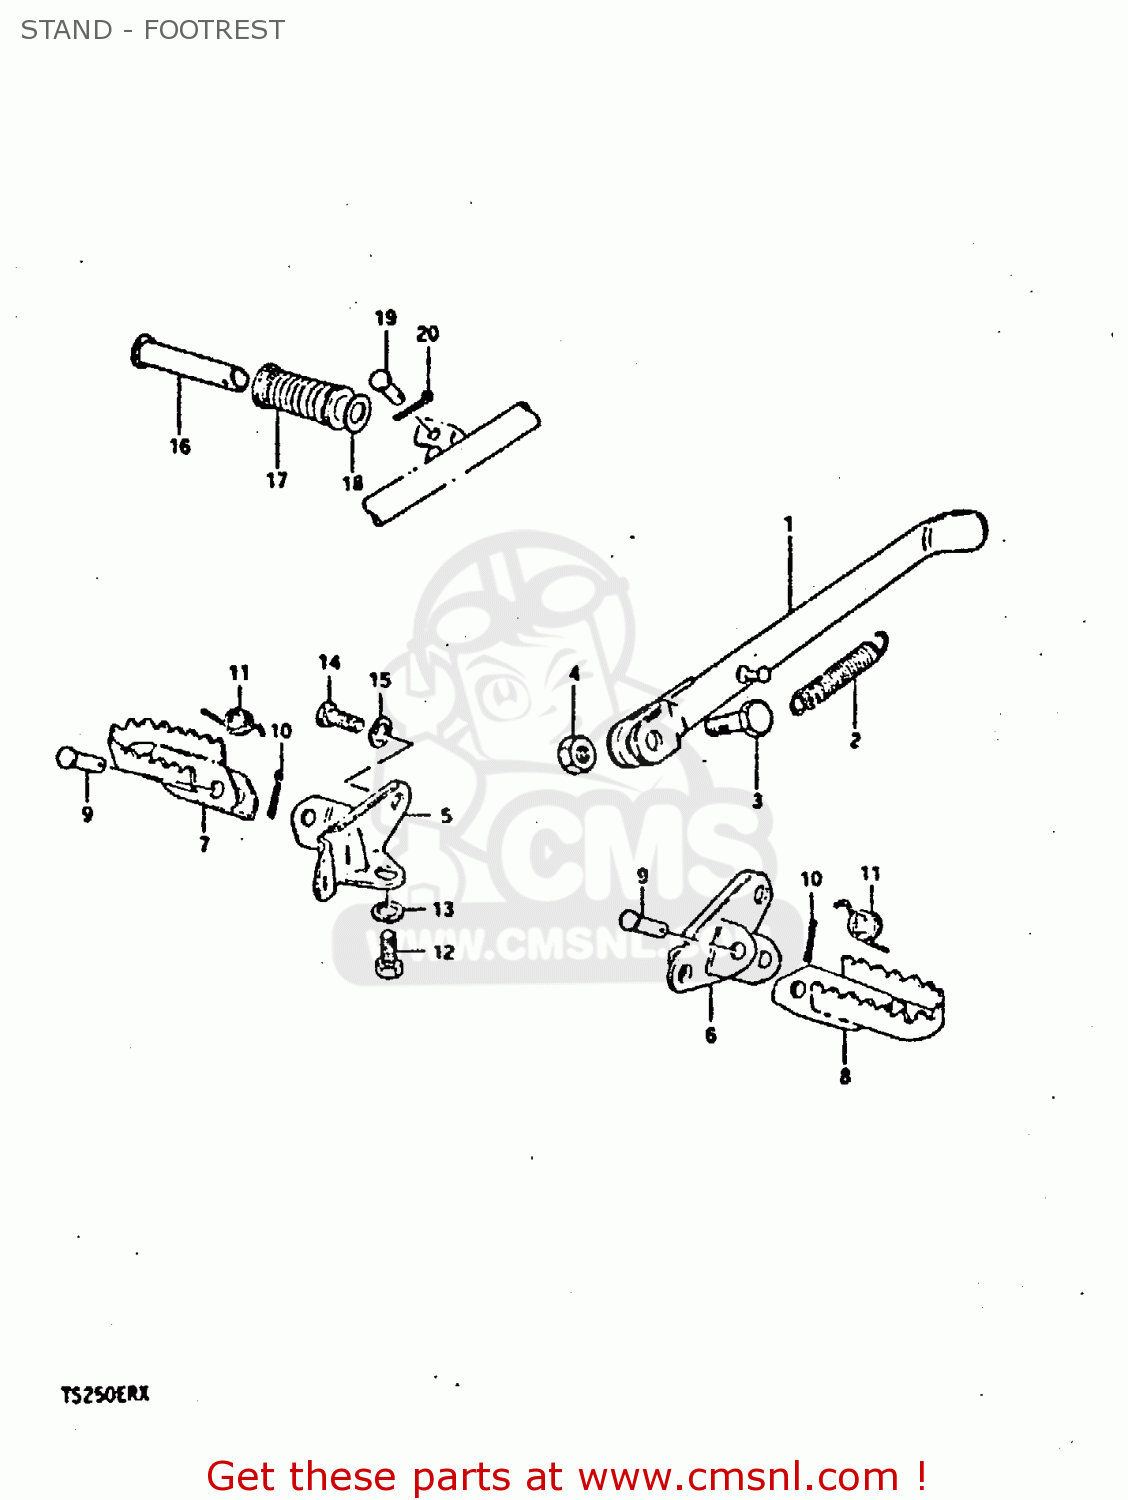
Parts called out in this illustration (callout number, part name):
1	STAND,PROP
2	SPRING
3	BOLT(10X30)
4	NUT
5	HOLDER,FRONT FOOTREST,RIGHT
6	HOLDER,FRONT FOOTREST
7	FOOTREST,FRONT
8	FOOTREST
9	PIN
10	PIN 20X20
11	SPRING
12	BOLT
13	WASHER,LOCK,8.
14	BOLT 8X16
15	WASHER,LOCK,8.
16	BAR,FOOTREST RUBBER
17	RUBBER,PILLION FOOTREST
18	WASHER (19.5X32X2)
19	PIN
20	PIN 20X20
